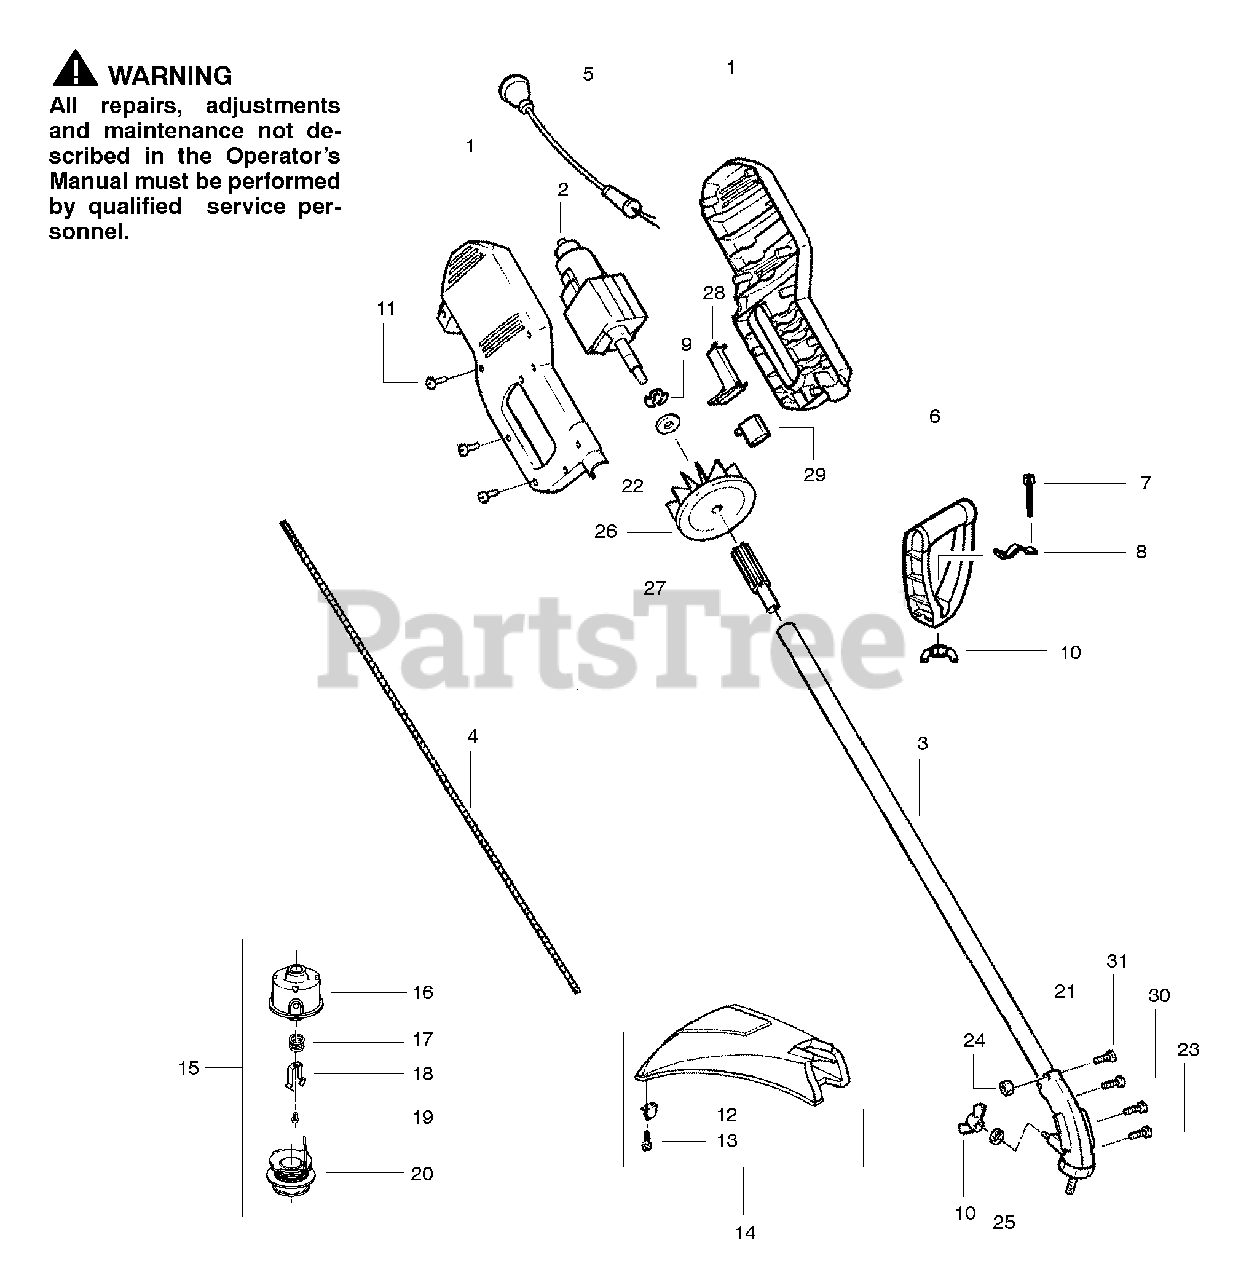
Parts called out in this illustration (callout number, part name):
1	Set-Housing
3	Assy-Tube
4	Shaft-Flex
5	Assy-Wiring Harness
6	Handle-Assist
8	Clamp-Assist Handle
9	Clip Retainer
10	Wingnut
12	Line Limiter
13	Screw-Line Limiter
14	Kit-Shield Ass'y.
15	Accy-Cutting Head
16	Assy-Hub
18	Retainer-Clip
19	Screw w/ Washer-Head
20	Accy-Spool w/Line
21	Assy-Gear Box
22	Washer-Drive Adaptor
27	Drive Adaptor Ass'y.
